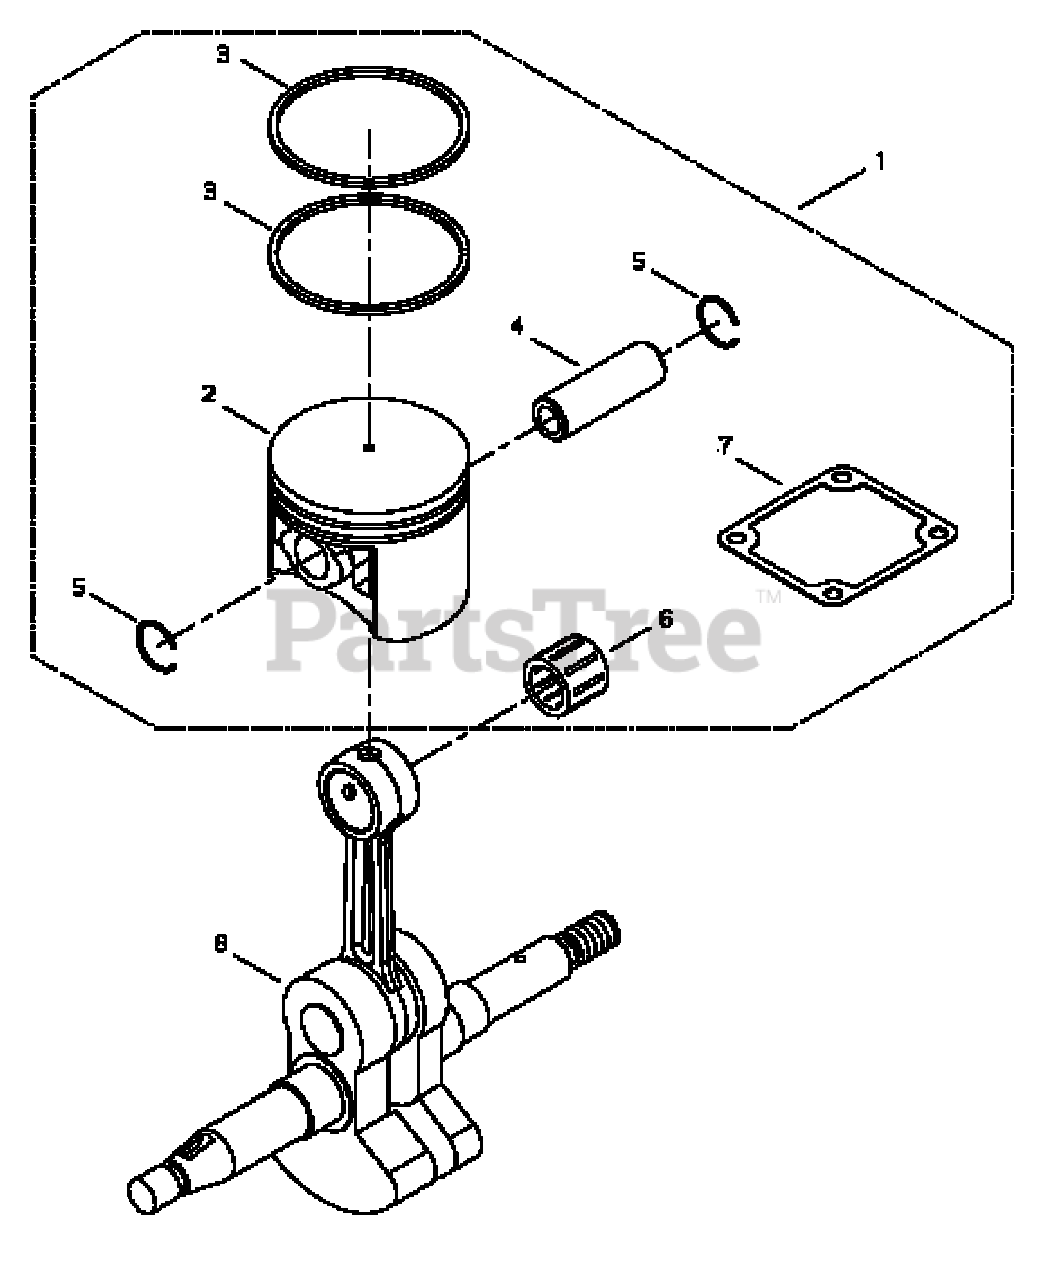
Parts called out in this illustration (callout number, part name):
1	PISTON KIT
2	PISTON
3	RING, PISTON
4	PIN, PISTON 10
5	RING, SNAP
6	BEARING, NEEDLE
7	GASKET, CYLINDER
8	CRANKSHAFT ASSY
